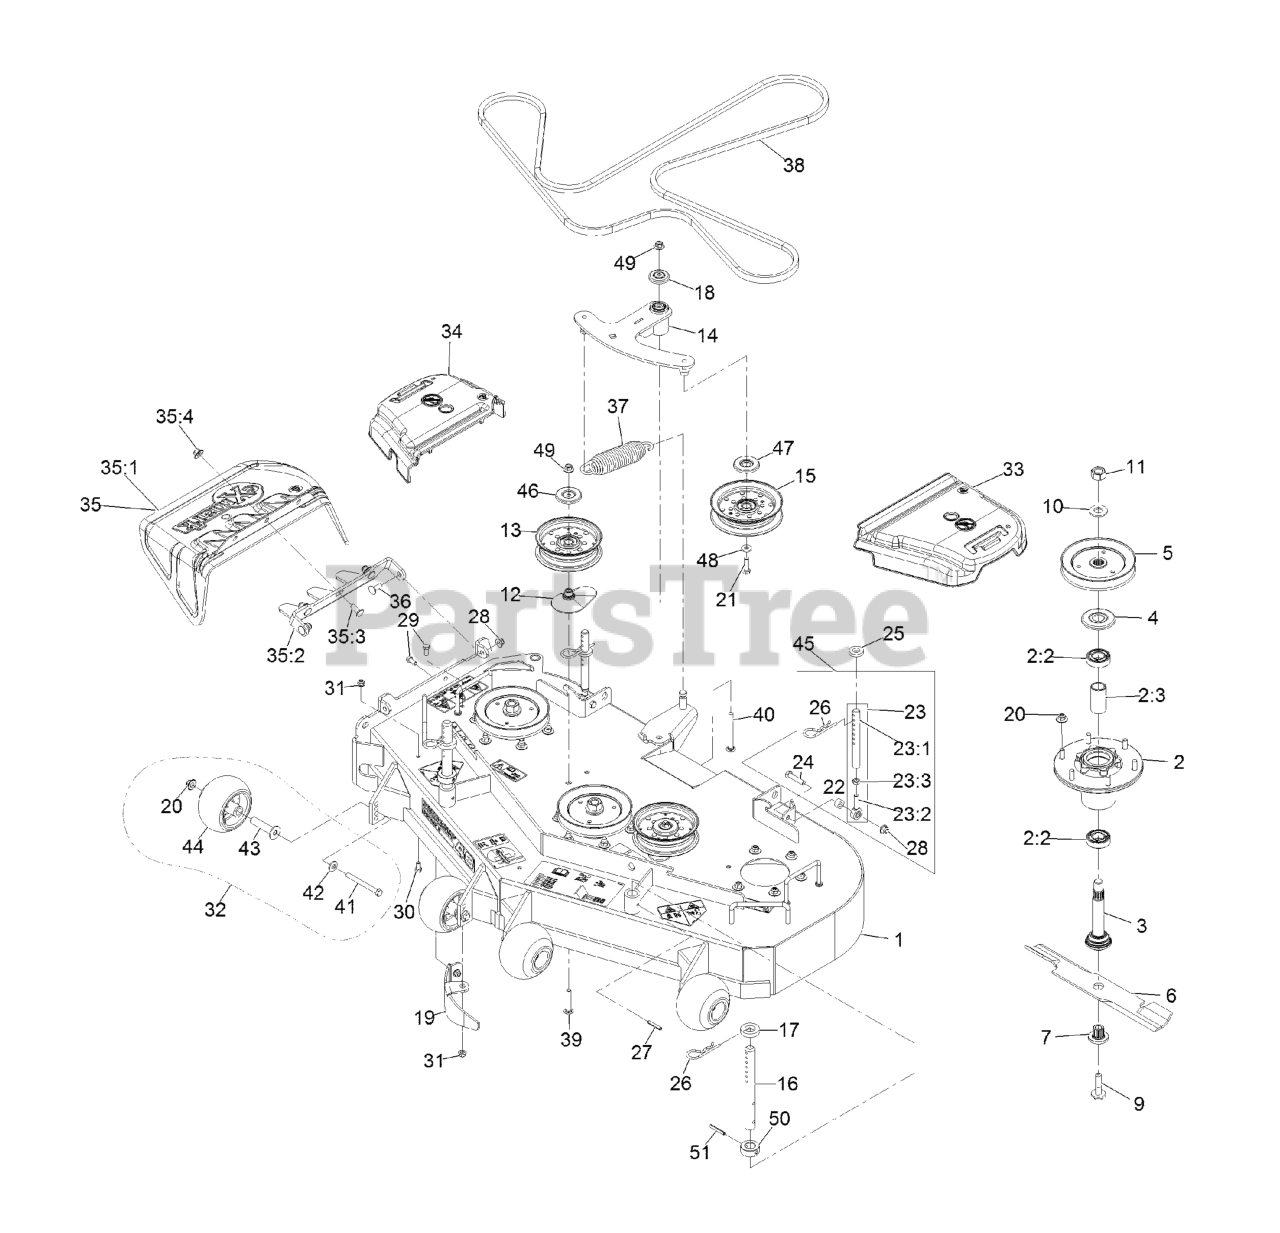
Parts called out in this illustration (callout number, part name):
1	ASM, DECK 48" W/DECALS
2	ASM-CUTTER HSG WITH BEARINGS
2:2	BEARING-BALL
2:3	SPACER-BEARING
3	ASM-SPINDLE AND SEAL
4	GUARD,BEARING TOP .989
5	SHEAVE,BLADE DRIVE 5.90
7	BUSHING,SPLINED
9	SCREW,SEMS 1/2-20 X 2.19
11	NUT-HEX
12	SPACER-PULLEY
13	IDLER-PULLEY, FLAT 5.00X1
14	ASM, DECK IDLER
15	IDLER-PULLEY, FLAT
16	Rod, Deck Support
17	SPACER-DECK SUPPORT
18	GUARD-TOP
19	BAFFLE, DOGLEG
20	Nut-Nyloc 3/8-16 Flg
21	SCREW-HH
23:1	LINK,SUPPORT
23:2	BALLJOINT
23:3	NUT-HJ
24	SCREW-HH
26	PIN,HAIR COTTER
28	NUT-HF, NI
29	SCREW-HH
30	SCREW-HH
31	NUT-HF, NI
32	KIT, ANTI-SCALP ROLLER
33	COVER-BELT, LH
34	COVER-BELT, RH
35	ASM, DISCHARGE CHUTE
35:1	CHUTE,DISCHARGE
35:2	BRACKET, DISCHARGE CHUTE
35:3	SCREW-CARR
35:4	Nut-Nyloc 3/8-16 Flg
36	SCREW-CARR
37	SPRING-EXTENSION
38	BELT, DECK
39	BOLT-CARR, SHORT NECK
40	SCREW-CARR
41	SCREW-HH 3/8-16 X 3 3/4 GR 8
42	WASHER-BELLEVILLE
43	AXLE, ROLLER
44	ROLLER-SCALP, ANTI
45	KIT,SUPPORT LINK W/PIN
46	SHIELD-DUST
47	SHIELD-GUARD, DUST
50	Collar, Deck Height Pin
51	PIN-ROLL
